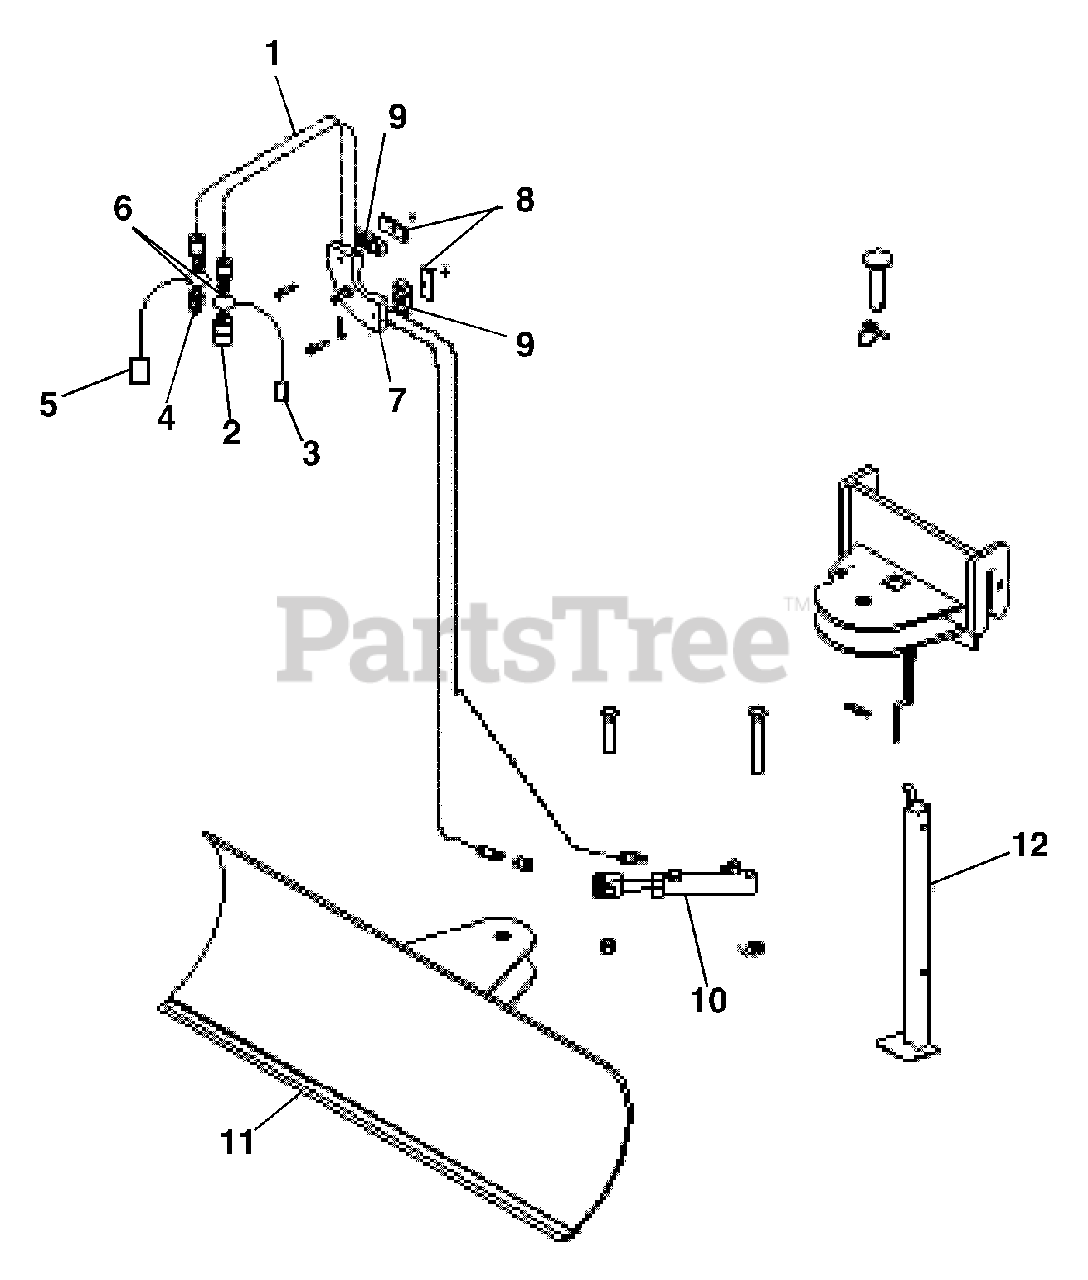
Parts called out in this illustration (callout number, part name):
1	Hose, Hydraulic .50
2	Coupling, Female Quick
3	Plug, Dust .500 Quick Coupler
4	Coupler, Male Quick
5	Cap, Dust .500 Quick Coupler
6	Seal, Bonded
7	Bracket, Attachment Hose-Assembly
8	Plate, Cover
9	Clamp, Dual Hose
10	Cylinder, 4N1 Bucket Right Hand
10	Seals, 4N1 Bucket Cylinder
11	Cutting Edge, Angle Blade
12	Stand, Angle Blade Support
